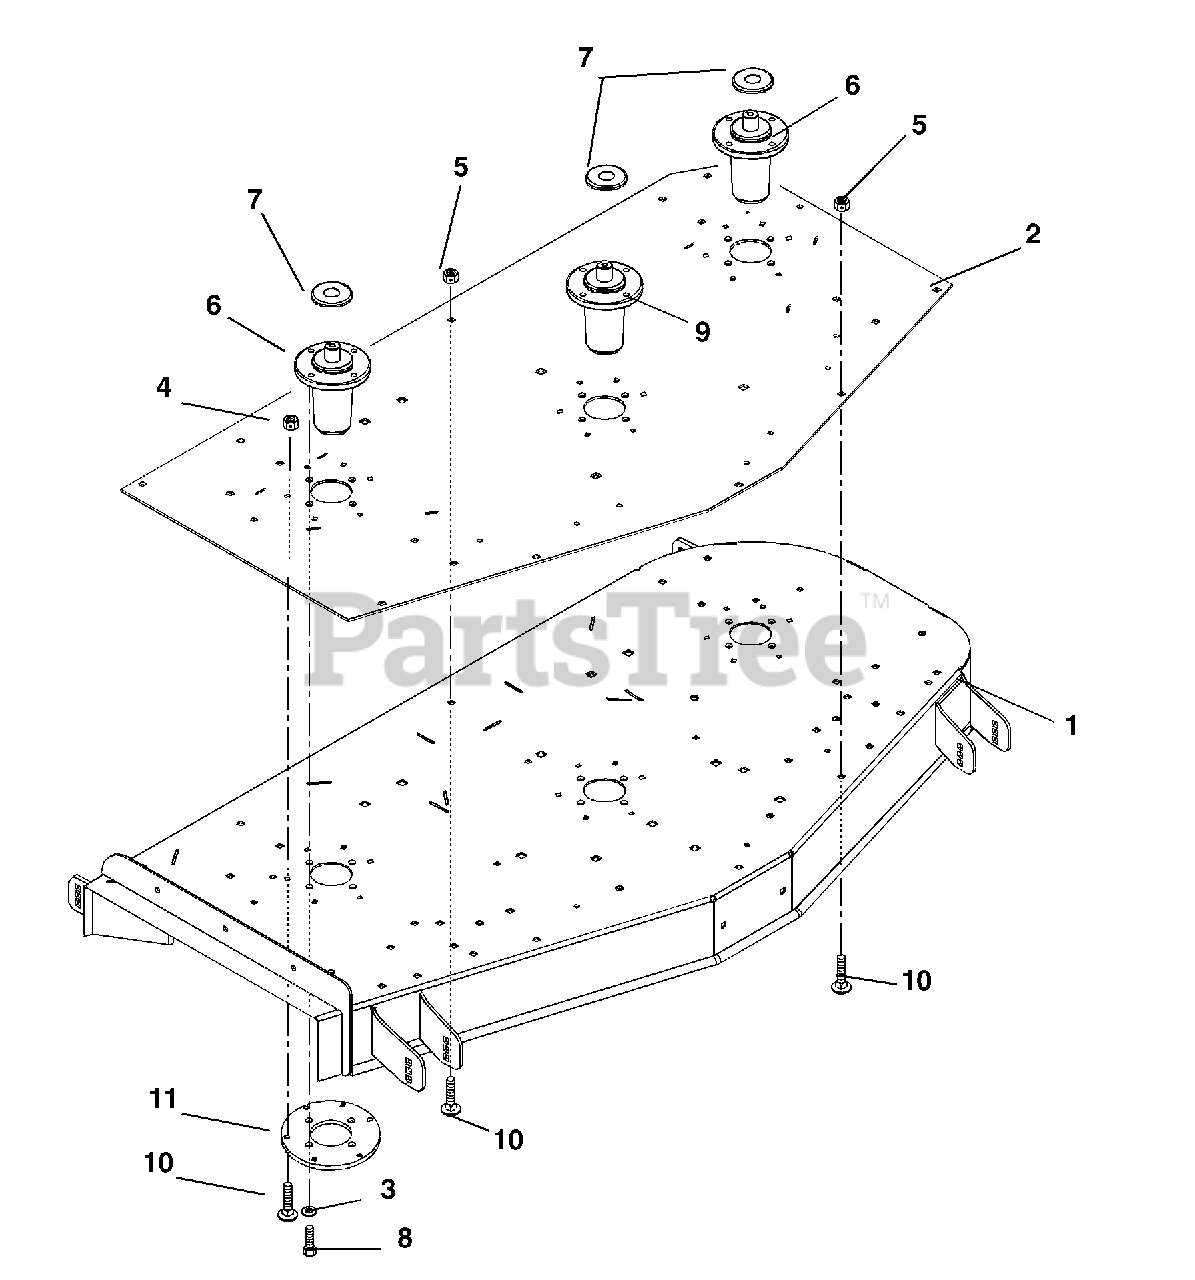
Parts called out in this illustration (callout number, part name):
1	Weldment, 72" Deck (Side Discharge)
2	Plate, 72" Reinforcment
3	Washer-Locking .38 x .094
4	Nut-Locking-Center .38-16
5	Nut-Locking-Nylon .38-16
6	Assembly, Spindle L-Hub
7	Slinger-Dust
8	Bolt-Hex .38-16 x 1.00 Grade 5
9	Spindle Assembly (Center)
10	Bolt-Round Head Square Neck .38-16 x 1.00 Grade 5
11	Plate, Spindle Reinforcement
